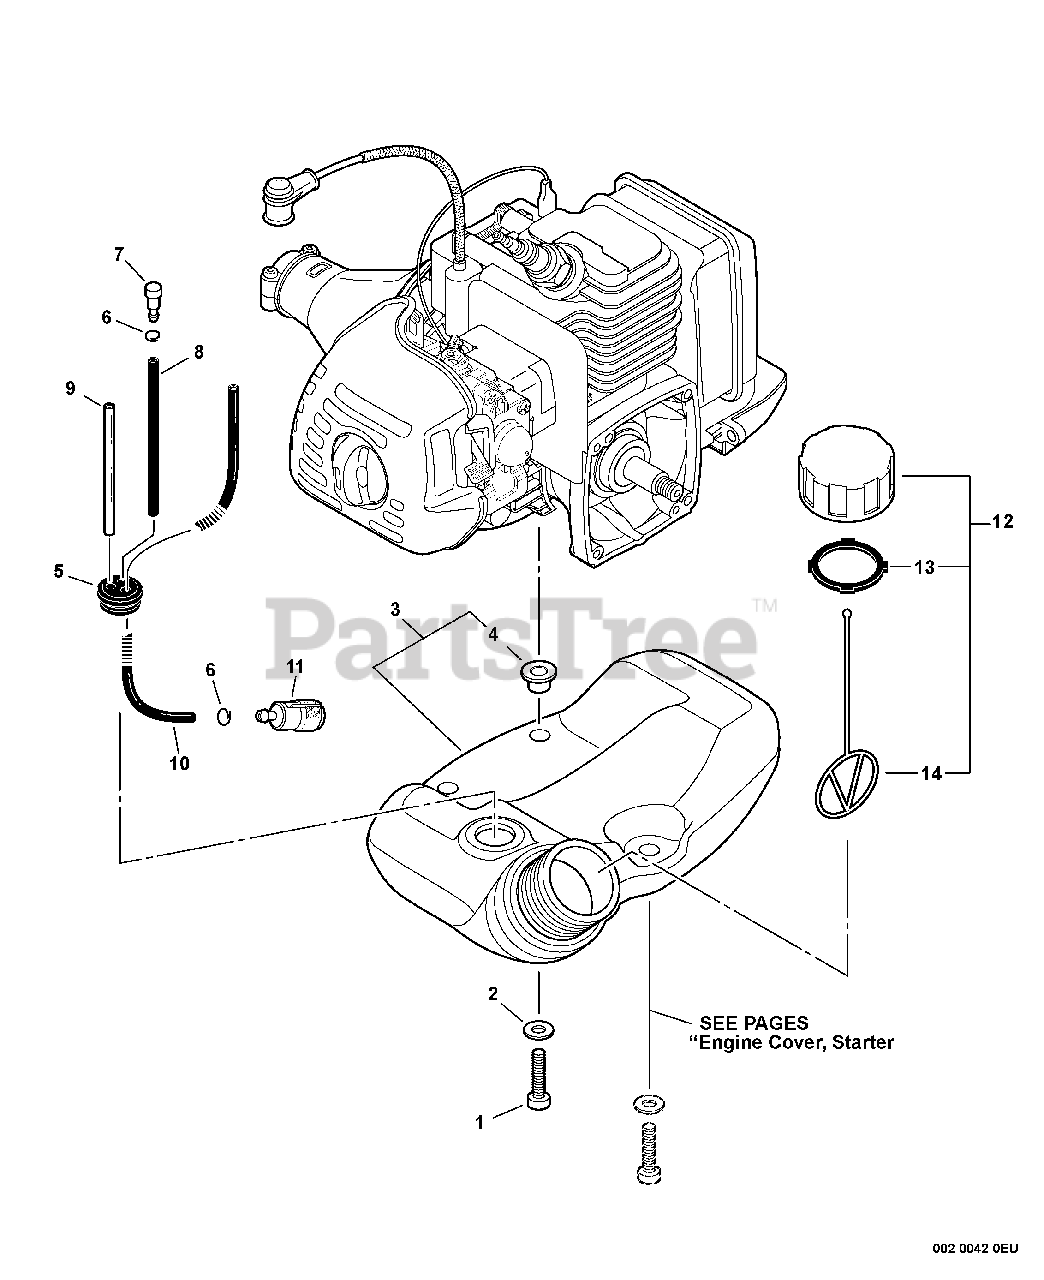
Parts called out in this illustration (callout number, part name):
1	BOLT, TORX 5×20
2	WASHER 5.5×12×0.8
3	TANK, FUEL
4	COLLAR 5
5	GROMMET, FUEL
6	CLIP 6 MM
7	VENT ASSY
8	PIPE, FUEL 3×5×90 BLACK
9	PIPE, FUEL 3×6×80 CLEAR
10	PIPE, FUEL
11	FILTER, FUEL
12	CAP ASSY, FUEL
13	GASKET, FUEL CAP
14	CONNECTOR, CAP L= 123
